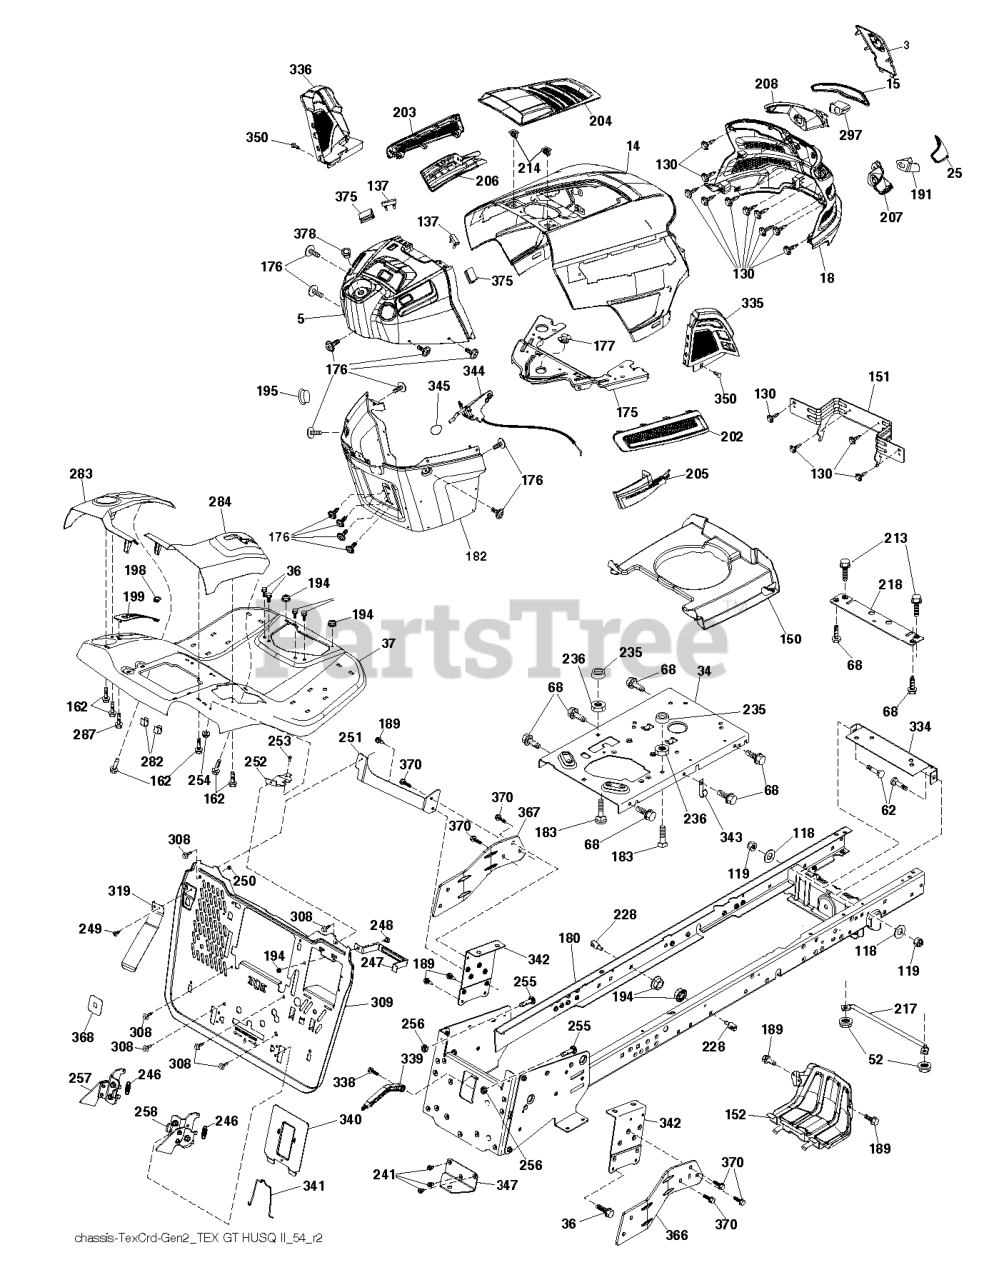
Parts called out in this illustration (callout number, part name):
3	APPLIQUE.SUBASM.GT.HUSQ.II
5	DASH.UPR.GT2.SM.PTO.MC.HR.498
14	HOOD.ASM.HUSQVARNA.GT.TEX.ORAN
15	LENS.HEADLIGHT.LH.GTII.2011
18	GRILLE SUBASM.GT.II.LOW.HDLGHT
25	LENS.HEADLIGHT.RH.GTII.2011
34	PLATE.ENGINE.10GA.CRD.GENII
36	SCREW 5/16"
37	FENDER.TEX.SRD.CRD.BASE
52	LOCKNUT
62	BOLT D
68	SCR 5/16-18 X 1/2 SELFTAP ZN
118	WASHER
130	SCREW.#10 X 0.750.BOS
137	BUMPER DASH
150	AIR DUCT.GTV2(1.66"RING HEIGHT
151	BRACKET.PIVOT.HOOD.GT.HUSQ.II
152	SHIELD.BROWNING.PNT.GT.V2
162	SCREW.HI-LO.CONSOLE
175	PLATE.PNT.CROSSMEMBER.HUSQ/PRE
176	SCREW.#10-24X5/8.RN.QU
177	BUSHING STEERING
180	CHASSIS WELDMENT.CRD2.BKP_BLTS
182	DASH DASH LOWER
183	BOLT.5/16-18X1-1/4 FULL THD
189	SCREW
191	INSERT.REFLECTIVE.RH.HUSQ.GTII
194	NUT LOCK HEX FLANGE 5/16-18
195	PLUG.HOLE.DASH.LOWER.12V.BLK
198	INDICATOR.DECK.LIFT.RED
199	PLATE DECK LIFT
202	VENT.SIDE.RH.GT.HUSQ.II.
203	VENT.SIDE.LH.GT.HUSQ.II.498
204	VENT.TOP.HUSQ.GT2
205	SIDE.TRIM.RH.GT.HUSQ.II
206	SIDE.TRIM.LH.GT.HUSQ.II.GRAY
207	HEADLIGHT.CUP.BEZEL.HUS.GT2.RH
208	HEADLIGHT.CUP.BEZEL.HUS.GT2.LH
213	HCS 5/16C X 3/4
214	CLIP.RETAINER.TINNER.
217	ROD.PIVOT.HOOD
218	X-PIECE.HOOD.STOP.NON/
228	STUD.FASTNER.W/ANTI-ROTATE
235	SPACER FENDER
236	NUT.CENTERLOCK.5/16-
241	SCREW 5/16-18X1
246	SPRING.LTCH.BGR.GEN2.5.CRD.TEX
247	STRAP.BATTERY.TCRD.GEN2.5X431
248	BOLT.CARR.5/16-18X1/2
249	SCREW.BUTTONHD.10-24X1/2.(2 2)
250	NUT 10-24 NYLOC
251	BRACKET.PNT.LH.SUPP.BKPLT.EDIP
252	BRACKET.PNT.RH.SUPP.BKPLT.EDIP
253	1/4-20X3/4 CARR BLT
254	NUT T
256	NUT.HEX.3/8-16
257	LATCH.ASM.BGR.LH.GEN2.5.STMPD
258	LATCH.ASM.BGR.RH.GEN2.5.STMPD
282	CLIP.RETAINER.CONSOLE.LT.HUSQ
283	CONSOLE.DECKLIFT.CRDII.498
284	CONSOLE.PEDAL.HYDRO
287	SCREW 1/4X20
297	INSERT.REFLECTIVE.LH.HUSQ.GTII
308	BOLT.5/16-18UNCX3/4 W/SEMS.BLK
309	BACKPLATE.TEXCRD2.5.BAGGER.479
319	LEVER.PRSNC.BGR.TEX.CRD.GEN2.1
334	BRACKET.ENGINE
335	COVER.LOWER.DASH.RH.BLACK
336	COVER-LH.LOWER.DASH.GT2.BLACK
339	LEVER LEVER BAGGER
340	BATTERY.DOOR.TCRD.GEN2.5.MS479
341	LATCH.BATTERY.DOOR.TCRD
342	SUPPORT.PNT.FENDER.CRD.TEX
343	CLIP CLIP
344	CONTROL.EZ.MULCH.TEX/CRD
345	RP KNOB.OVAL.TAPERED.3/8-16BLK
347	HITCH HITCH TOW TEX CRD GEN 2
350	CLIP.X-MAS.TREE
366	BRACKET.RH.FRONT.BAGGER.BLACK
367	BRACKET.LH.FRONT.BAGGER.BLACK
368	FULL.LEVER.BAGGER.TEX.CRD
370	SCREW 3/8-16X1
375	BUMPER CLIP-ON. DASH 1"
378	BUSHING FLANGE; PLASTIC
